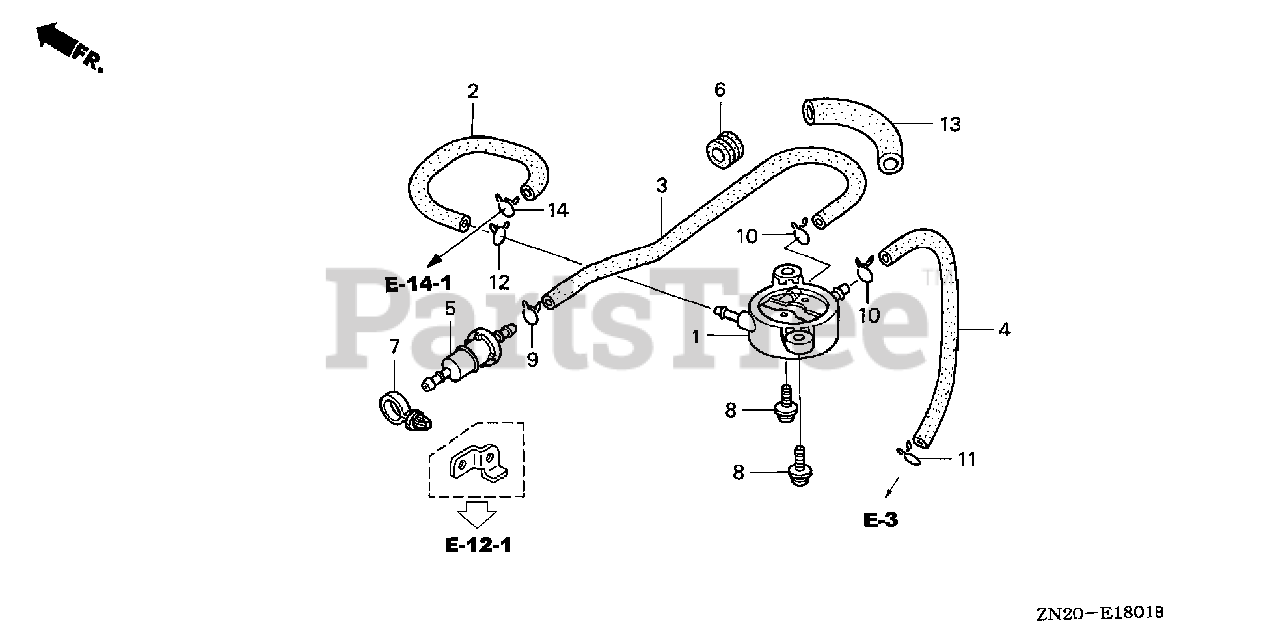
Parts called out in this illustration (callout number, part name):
1	PUMP ASSY., FUEL
2	TUBE, FUEL
3	TUBE B, FUEL
4	TUBE, DIAPHRAGM
5	STRAINER, FUEL
6	GROMMET, RESERVE TANK
7	CLIP, WIRE HARNESS
8	SCREW-WASHER (6X16)
9	CLIP, TUBE (B8)
10	CLIP, TUBE (B10)
11	CLIP, TUBE (C9)
12	CLIP, TUBE (C11)
13	BULK HOSE, VINYL (11X13X3000) (11X13X50)
14	CLIP, TUBE (B10)
14	CLIP, TUBE (C11)
